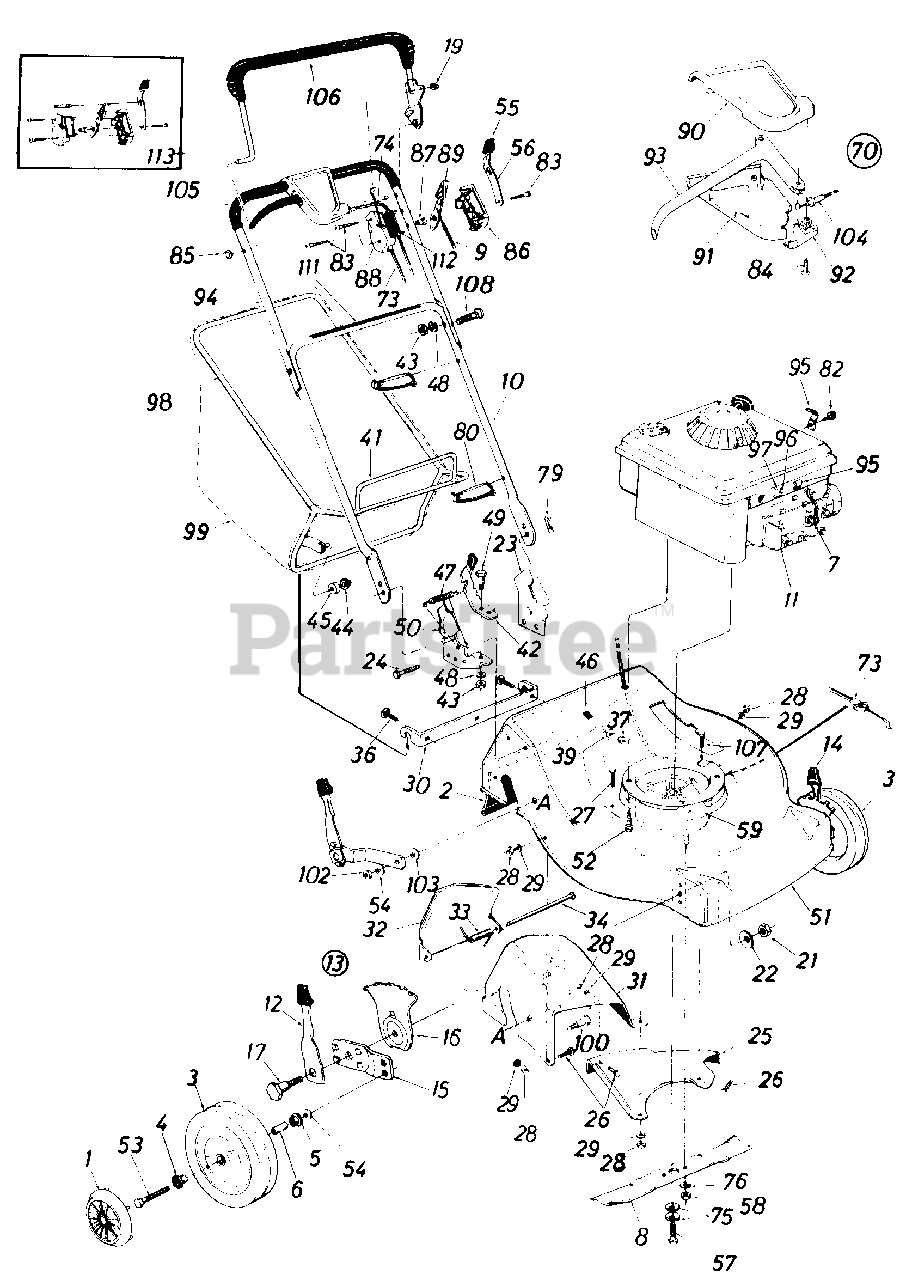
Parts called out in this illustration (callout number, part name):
1	Hub Cap-Plastic
2	Rear Flap Ass'y.
3	Front Wheel Ass'y. Comp.
4	Bearing
5	Bearing
6	Spacer
7	Spark Plug Boot
8	22" Blade
9	Throttle Control Wire-58"
10	Lower Handle
11	Engine
12	Spring Lever Ass'y. w/Knob
13	Height Adjust. Ass'y.-R.H.
14	Height Adjust. Ass'y.-L.H.
15	Pivot Bar
16	Index Plate
17	Shld. Bolt .50" Dia. x .375"
19	Push Cap
21	Hex Nut 3/8-16 Thd.*
22	Bell-Wash. .39" I.D. x 1.38" O.D.
23	Handle Brkt. Ass'y.-L.H.
24	Hex Wash. Hd. AB-Tap Scr. 1/4" x .62" Lg.
25	Rear Baffle-L.H.
26	Carriage Bolt 1/4-20 x .50"*
27	Hex Bolt 1/4-20 x .88" Lg.*
28	Hex Nut 1/4-20 Thd.*
29	L-Wash. 1/4" I.D.*
30	Grass Catcher Hitch Brkt.
31	Rear Chute Baffle Ass'y.
32	Chute Door
33	Torsion Spring
34	Hinge Pin .250" Dia. 7.88" Lg.
36	Carriage Bolt 1/4-20 x .75"*
37	Sems Nut 1/4-20 Thd.
39	Fl-Wash. .285" I.D. x 1.25"
43	Hex Nut 5/16-18 Thd.*
44	Push Nut 3/8" Rod
45	Plastic Roller
47	Extension Spring .33" O.D. x 1.12" Lg.
48	L-Wash. 5/6" I.D.*
49	Shld. Bolt .437" Dia. x .162"
50	Handle Brkt. Ass'y.-R.H.
51	22" Deck Ass'y.
52	Hex Wash. Hd. TT-Tap Scr. 3/8-16 x 1.0" Lg.
53	Axle Bolt
54	Bell-Wash. .44" I.D. x .88"
55	Spring Lever Knob
56	Lockout Lever
57	Hex Bolt 3/8-24 x 2 00n Lg. (Grade 8)
58	Hex Nut 3/8-24 Thd. (Grade 8)
59	Blade Brake Clutch Ass'y. Comp.
70	Clutch Control Housing- Comp.
73	Clutch Cable-46"
74	Lock Pin .314" Dia. x 1.70"
75	Bell-Wash. .44" I.D. x 88"
76	L-Wash. 3/8" I.D.
79	Intern. Cot. Pin 5/16" Dia.
80	Cable Tie
82	Hex B-Tap Scr. #10 x .38" Lg.
83	Truss Mach. Scr. #12 x 1.50"
84	Flat "C"-Sunk Hd. Scr. #10 x 1.0" Lg.
85	Cap Speed Nut 5/16" Rod
86	Control Panel Half
87	Control Disc Pin
88	Clutch Panel Half
89	Throttle Control Lever
90	Control Cover Half-Upper
91	Control Cover Half-Lower
92	Cable Mtg. Cap
93	Control Lever
94	Upper Handle
95	Casing Clamp
96	Hex B-Tap Scr. #10 x .62" Lg.
97	Casing Clamp
98	Grass Catcher Upper Frame
99	Grass Bag (without Flip Top)
100	Shld. Bolt .500" Dia. x .685"
102	Hex Jam Nut 3/8-16 Thd.
103	Bell-Wash. .400" I.D.
104	Clutch Cable-50"
106	Blade Clutch Control Handle
107	Hex Wash. Hd. Self-Tap Scr. 1/4-20 x .75" Lg.
108	Curved Hd. Carr. Bolt 5/16-18 x 1.38
111	Instruction Label-Handle
112	Control Label-Throttle
113	Control Housing Comp.
